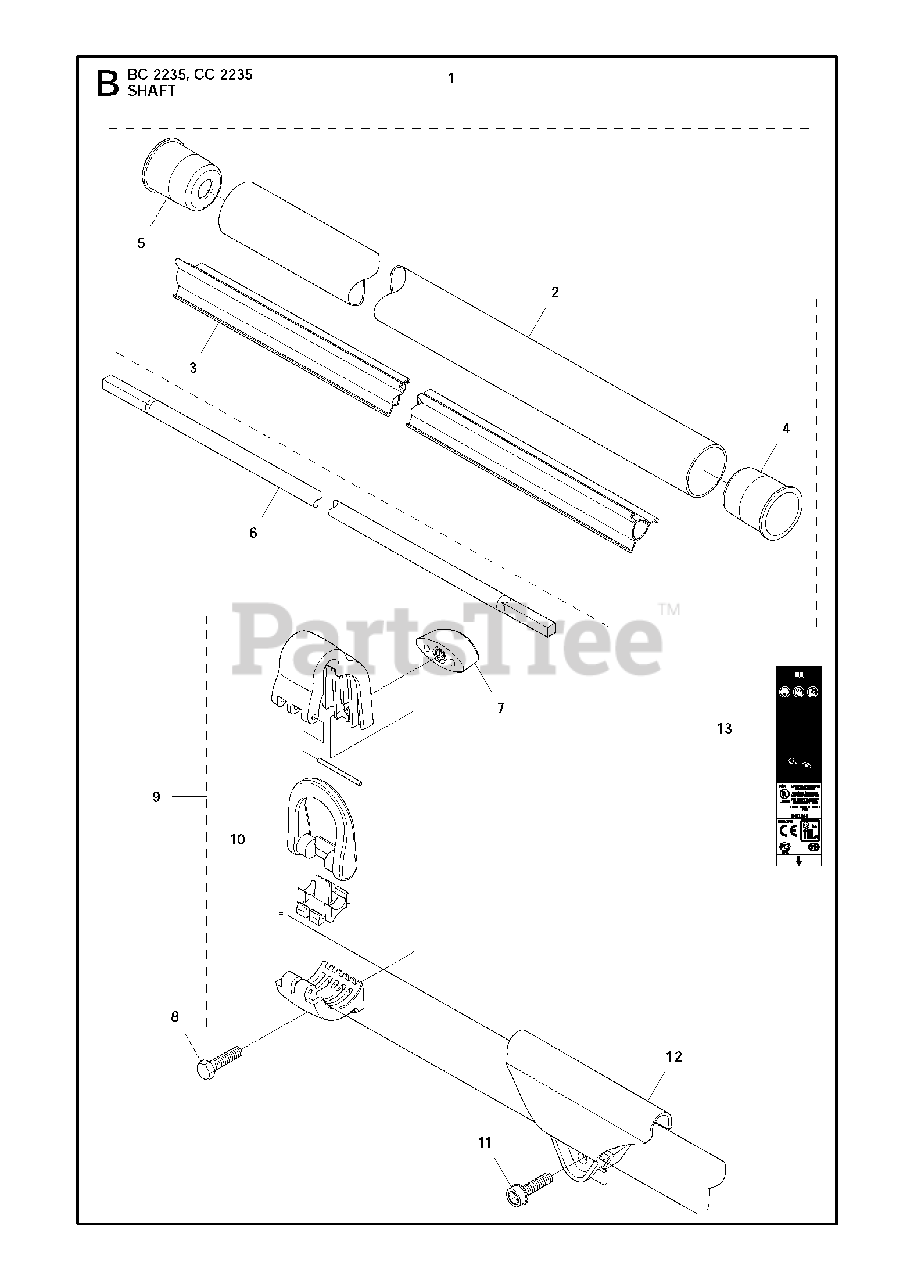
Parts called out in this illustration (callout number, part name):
2	RP TUBE
3	GUIDE
4	PLUG
5	PLUG
8	SCREW M6S 5X20
10	LOOP
13	LABEL WARNING
